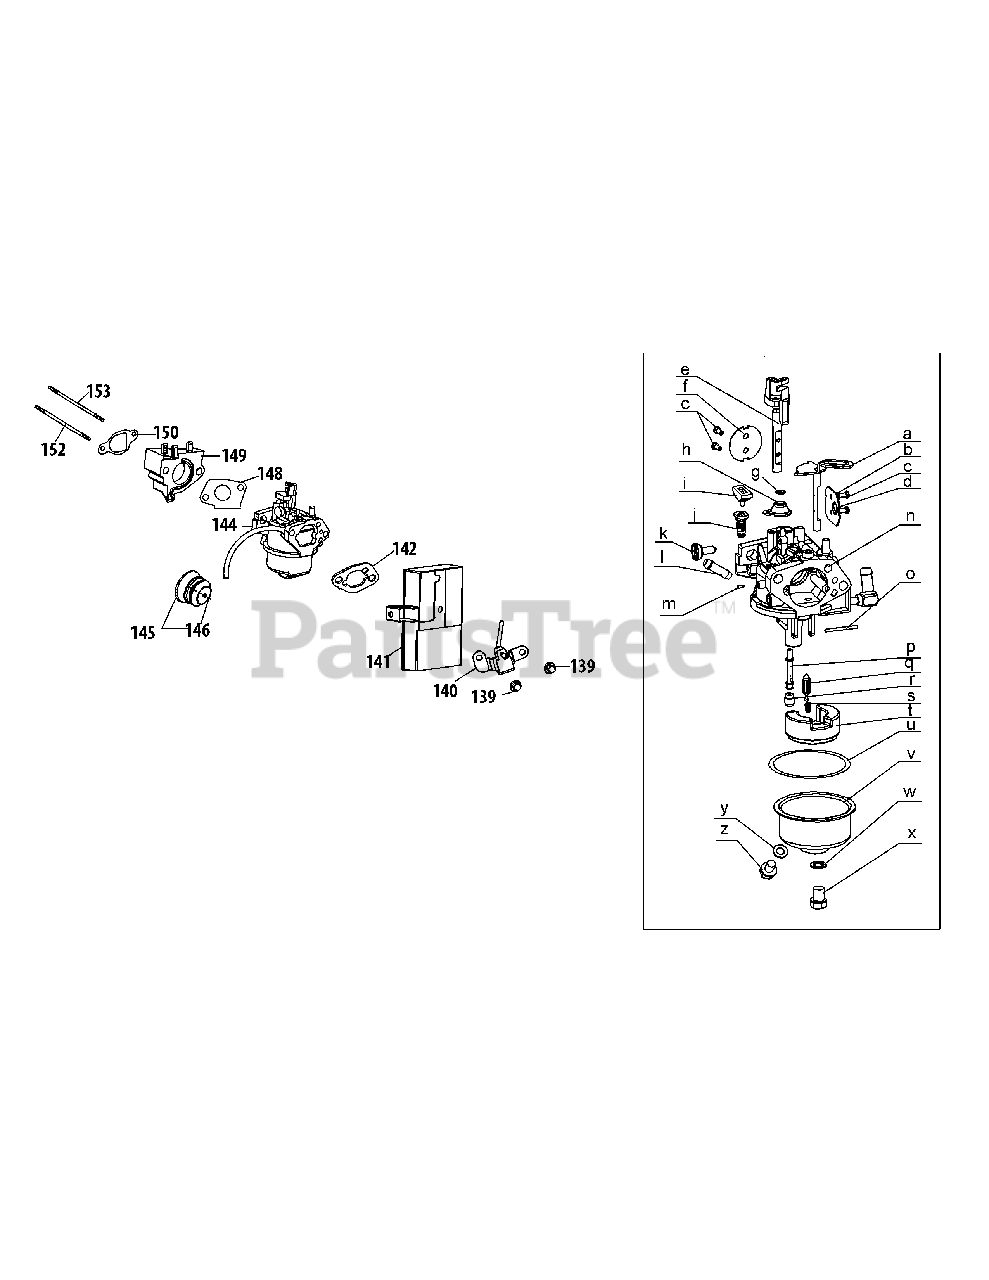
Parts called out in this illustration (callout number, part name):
140	CHOKE CONTROL
141	HEATER BOX
142	GASKET,AIR CLEANER
143	PRIMER HOSE
144	CARBURETOR ASSEMBLY
145	PRIMER ASSEMBLY
148	CARBURETOR GASKET
149	CARBURETOR INSULATOR
150	CARBURETOR INSULATOR GASKET
151	AIR SHIELD
152	STUD M6-8×118
153	STUD M6-8×100
